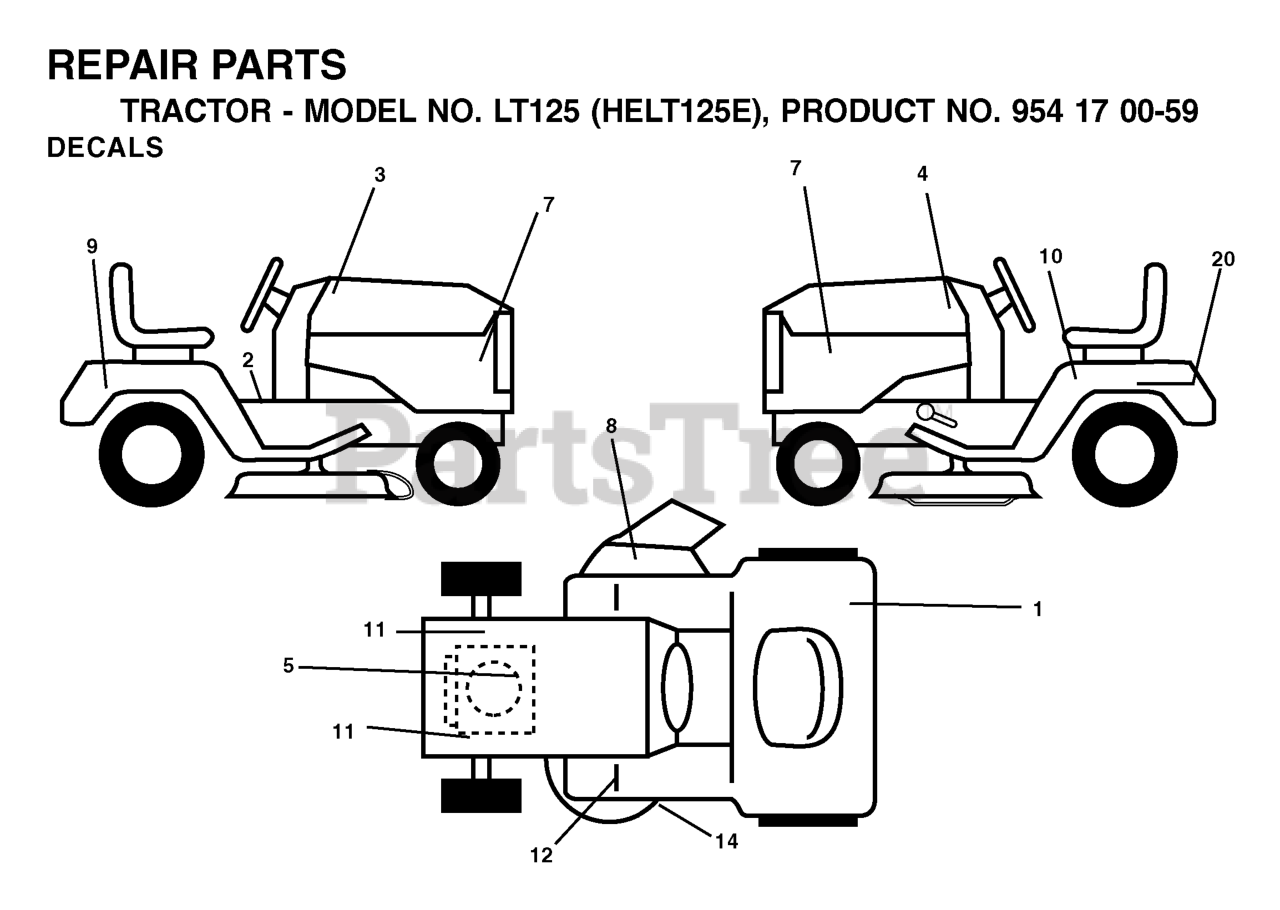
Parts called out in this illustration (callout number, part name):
1	Decal, Fender 100 DB/CE
2	DECAL PARK BRAKE
5	DECAL ENGINE HP
7	DECAL PNL SIDE
8	DECAL.INTERNATIONL.CUTFINGER
9	DECAL FENDER HUSQ
10	DECAL READ OWNER'S MAN SYMS
12	DECAL
14	DECAL V-BELT SCHEMATIC
20	DECAL BTRY SYMBOLS
